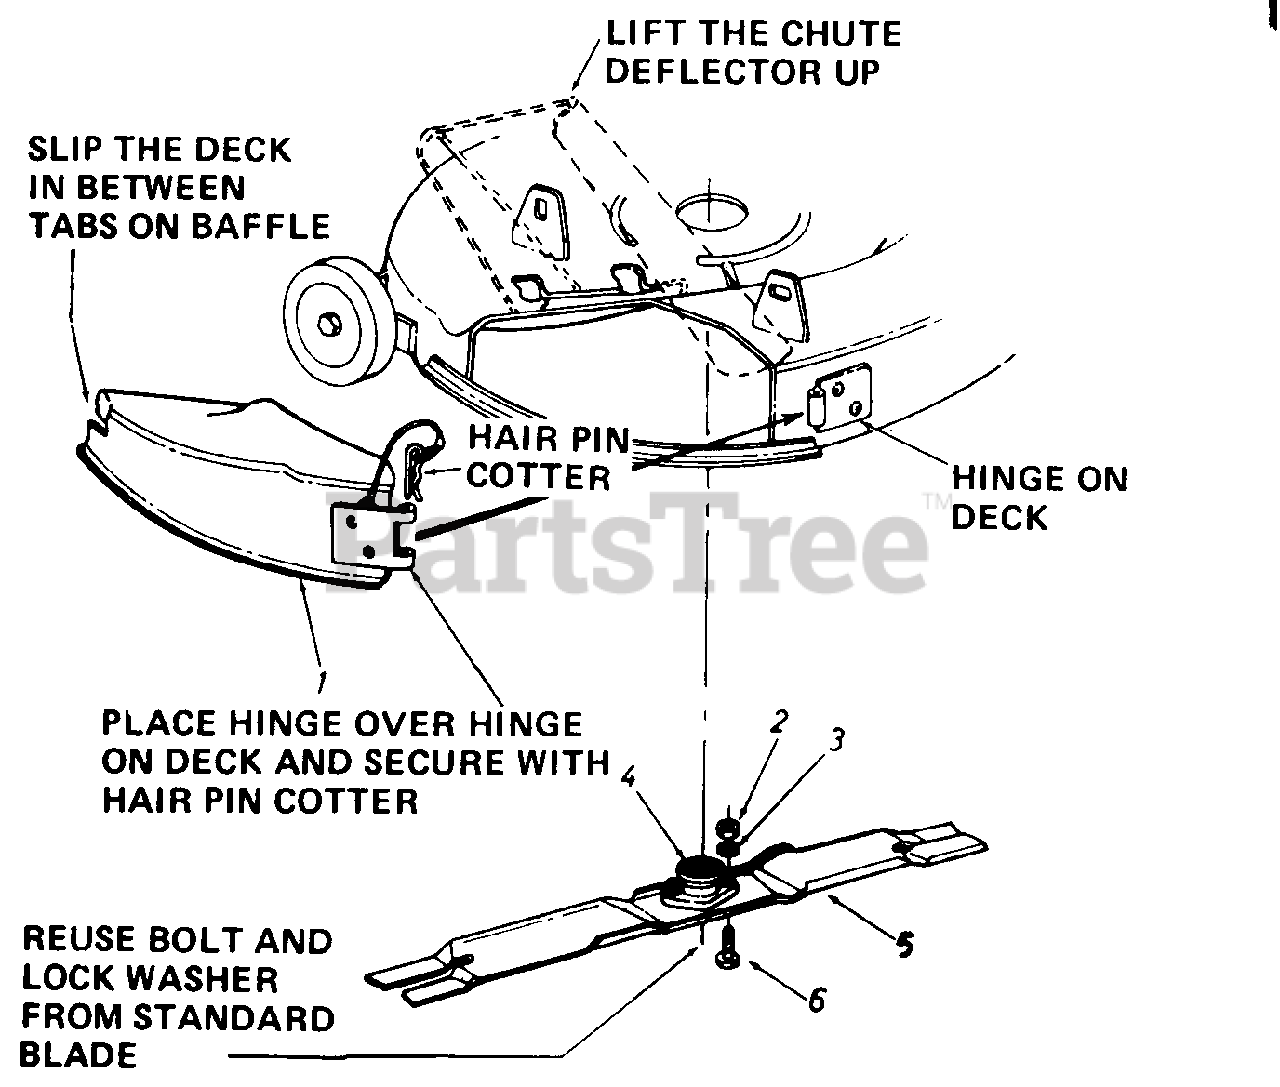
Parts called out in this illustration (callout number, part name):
1	30" Mulching Baffle Ass'y.
2	Hex Nut 5/16-24 Thd.*
3	L.-Wash. 5/16" I.D. *
4	Kit-Blade Adapter Ass'y.
5	30" Mulching Blade
6	Hex Bolt 5/16-24 x 1.0" Lg. H.T.
